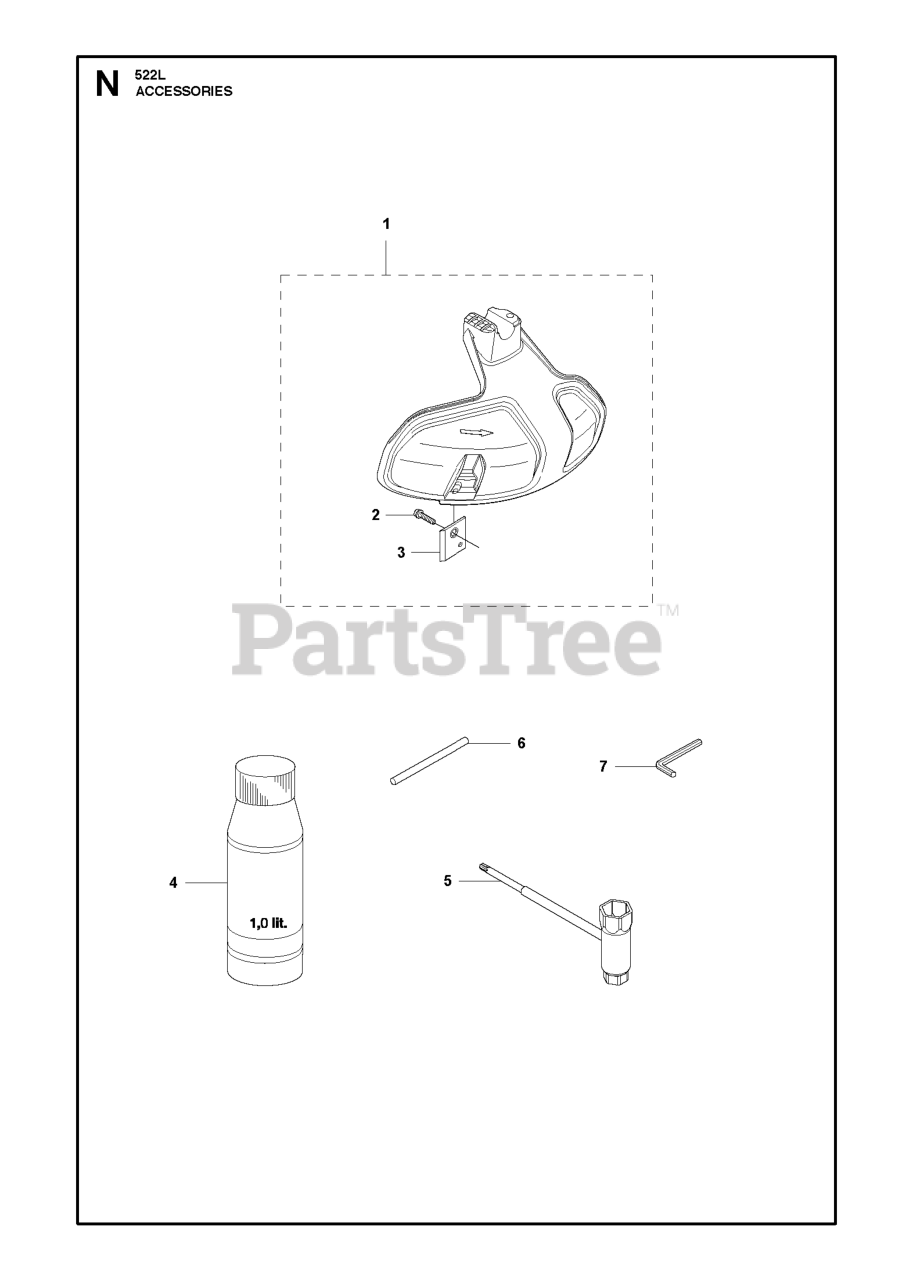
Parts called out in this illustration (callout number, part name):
1	TRIMMER GUARD ASSEMBLY
3	LINE CUTTER
5	COMBINATION WRENCH TORX
6	LOCKING PIN
